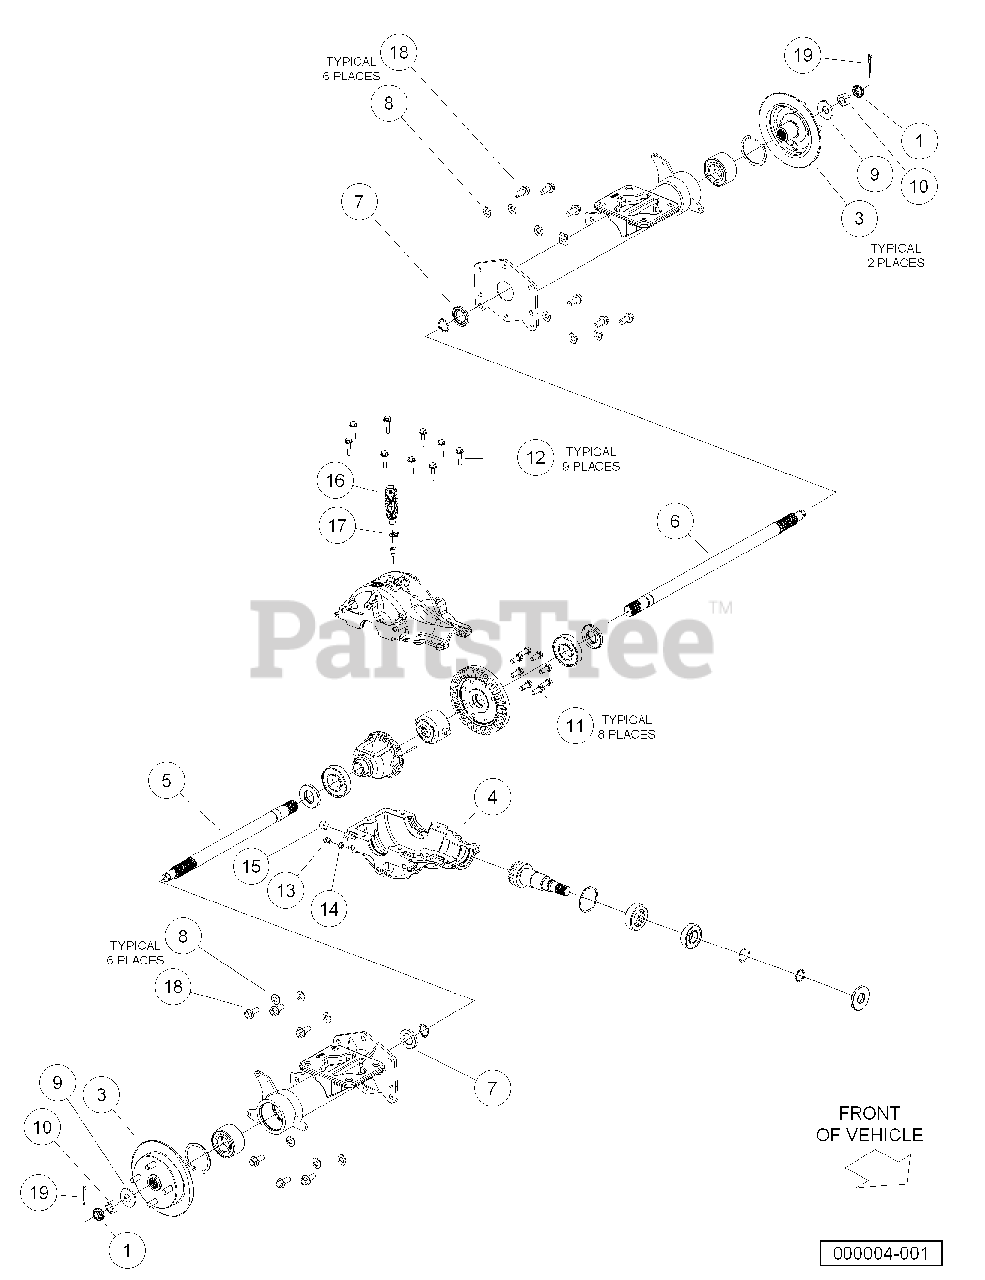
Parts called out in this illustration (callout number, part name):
1	Axle, Rear, Guard Mounts
2	Locking Cap, Nut
3	Assy, Rotor, Brake, Rear
4	Gearcase, Lower, Machined
5	Axle, Right-hand
6	Axle, Left-Hand
7	Washer,counterbored 51 X 30
8	Washer, Bellevle, 1.063 X .043
9	Washer, Belleville, 49 X 4 .
10	Nut, Hex, M20 X 1.5 , Modified
11	Screw, M10 X 25
12	Screw,hex Flange, M8 X 35
13	Plug,3/8-16, Hex Flange
14	Washer, .625 X .382 X .60
15	Plug, Square Skt, 1/12-14, Ptf
16	Bellows, Vent, Upper Housing
17	Clamp, Hose, Dw-9.5
18	Screw, Hex Fl, M12 X 1.75 X 30
19	Pin, Cotter, 5/32 X 1.25
